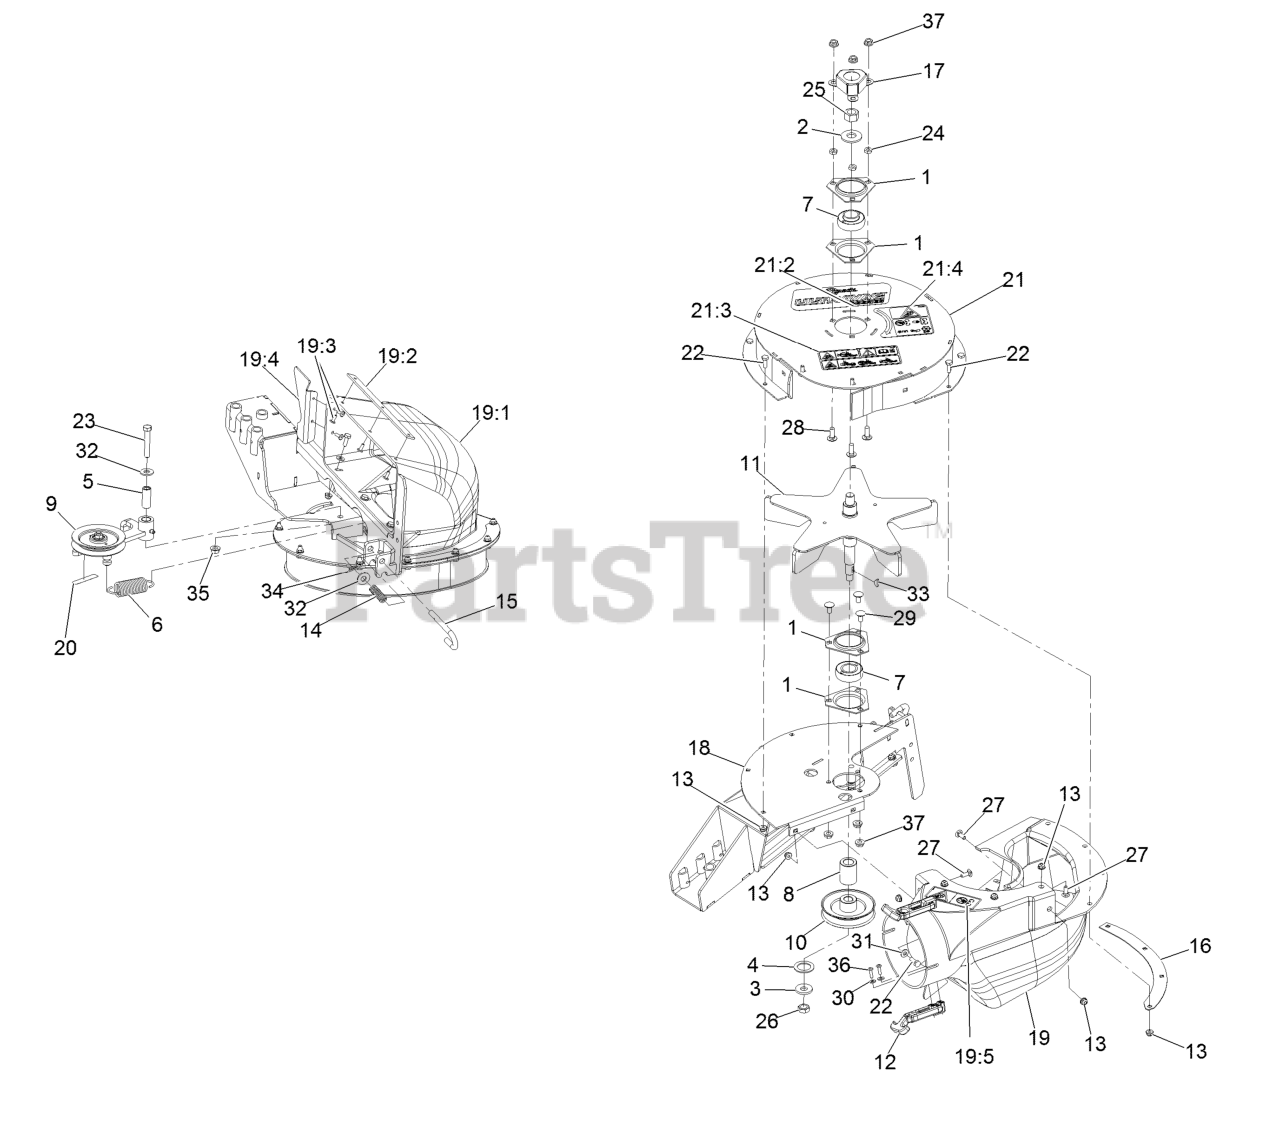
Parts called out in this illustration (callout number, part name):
1	HOUSING-FLANGE
2	WASHER-SPRING
3	WASHER-SPRING
4	WASHER-SPACER
5	BUSHING
6	SPRING-IDLER
7	BEARING
9	Asm, Idler
10	SHEAVE-BLOWER
11	IMPELLER
12	LATCH-RUBBER
14	SPRING-COMPRESSION
15	PIN-LATCH
16	PLATE-BACKING
17	COVER-NUT
18	BLOWER FRAME ASM
19	BLOWER CHUTE ASM
19:1	CHUTE-BLOWER, SMALL
19:2	PLATE-REINFORCEMENT
19:3	RIVET-BLIND
19:4	PLATE-FILLER
19:5	Decal-Warning
20	DECAL-WARNING
21	UPPER-HOUSING W/DECAL
21:2	DECAL-ULTRAVAC E-SERIES
21:3	DECAL-WARNING
21:4	DECAL-WARNING
22	SCREW-HH
23	SCREW-HH
24	NUT-JAM
25	NUT-HEX
26	NUT-JAM
27	BOLT-CARR
28	BOLT-CARR
29	SCREW-CARR
30	WASHER-FLAT
31	WASHER-FLAT
32	WASHER-FLAT
33	KEY-WOODRUFF
35	NUT-HHF, WHIZ
36	SCREW-PPH
